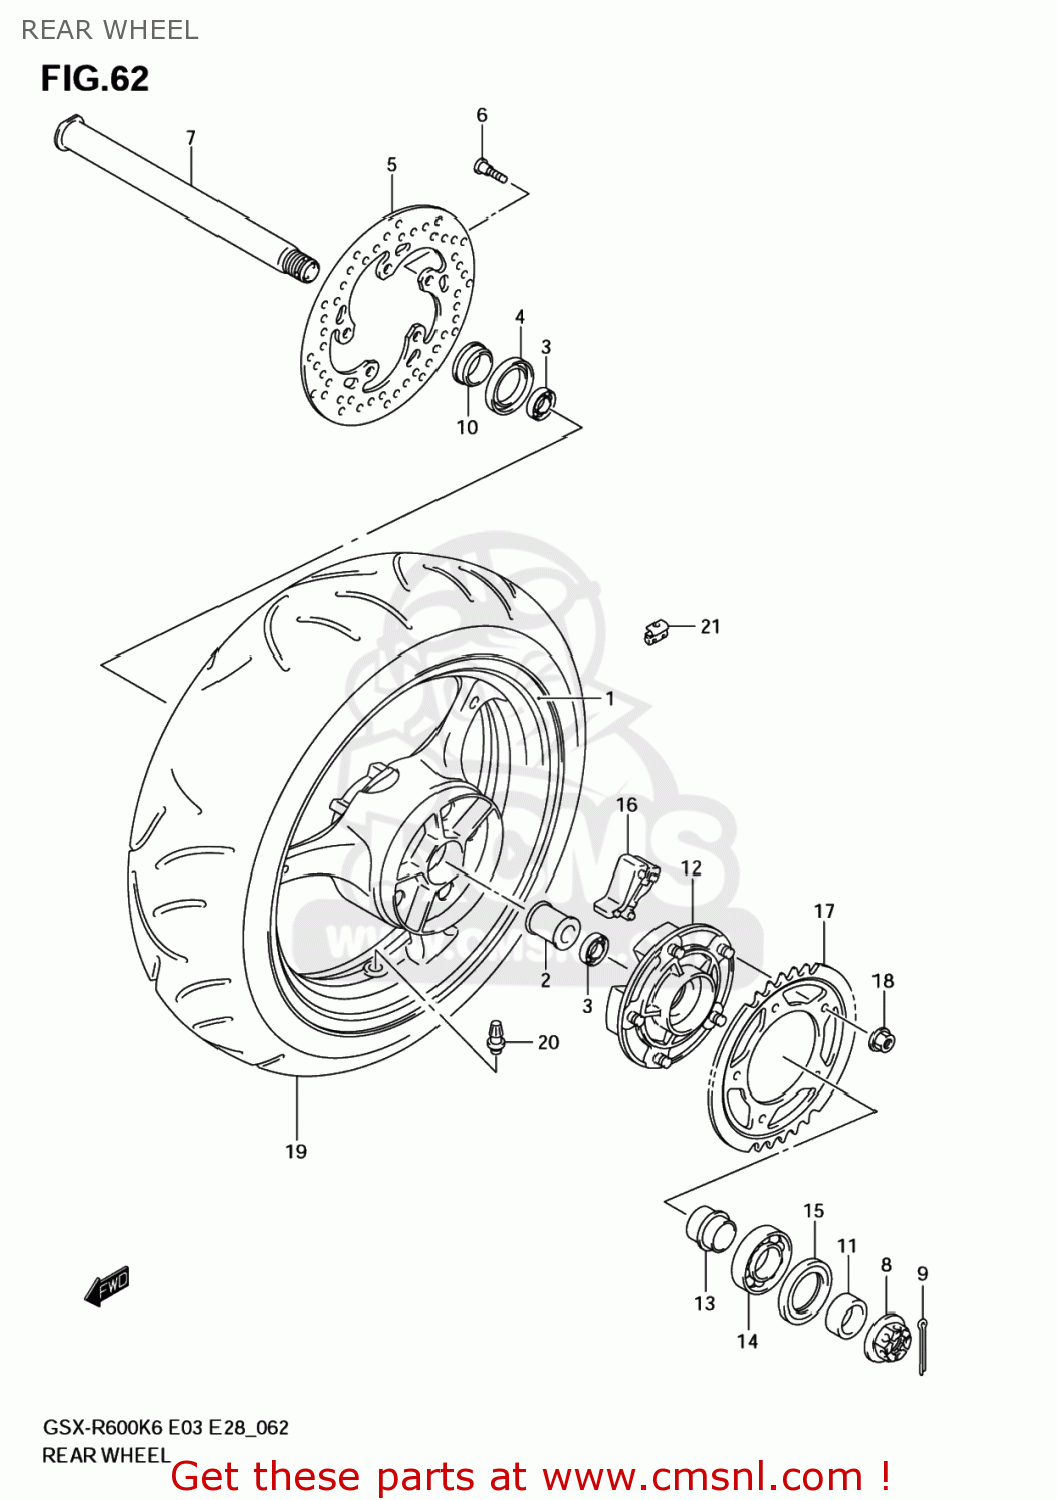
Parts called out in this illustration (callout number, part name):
1	WHEEL,RR(17M/CXMT5.50)
2	SPACER,RR WHEEL BEARING
3	BEARING(28X52X12)
4	SEAL,OIL(37X52X8)
5	DISC,RR BRAKE
6	BOLT(8X21)
7	AXLE,REAR
8	NUT
9	PIN
10	SPACER,RR AXLE,R
11	SPACER,RR AXLE,L
12	DRUM COMP,REAR
13	RETAINER,REAR
14	BEARING
15	SEAL,OIL(39X65X7)
16	ABSORBER,RR HUB SHOCK
17	SPROCKET,REAR(
18	NUT
19	TIRE,RR(180/55 ZR17M/C 73W)
20	VALVE ASSY,WHEEL RIM(TR412)
21	BALANCER, WHEEL NO.1
